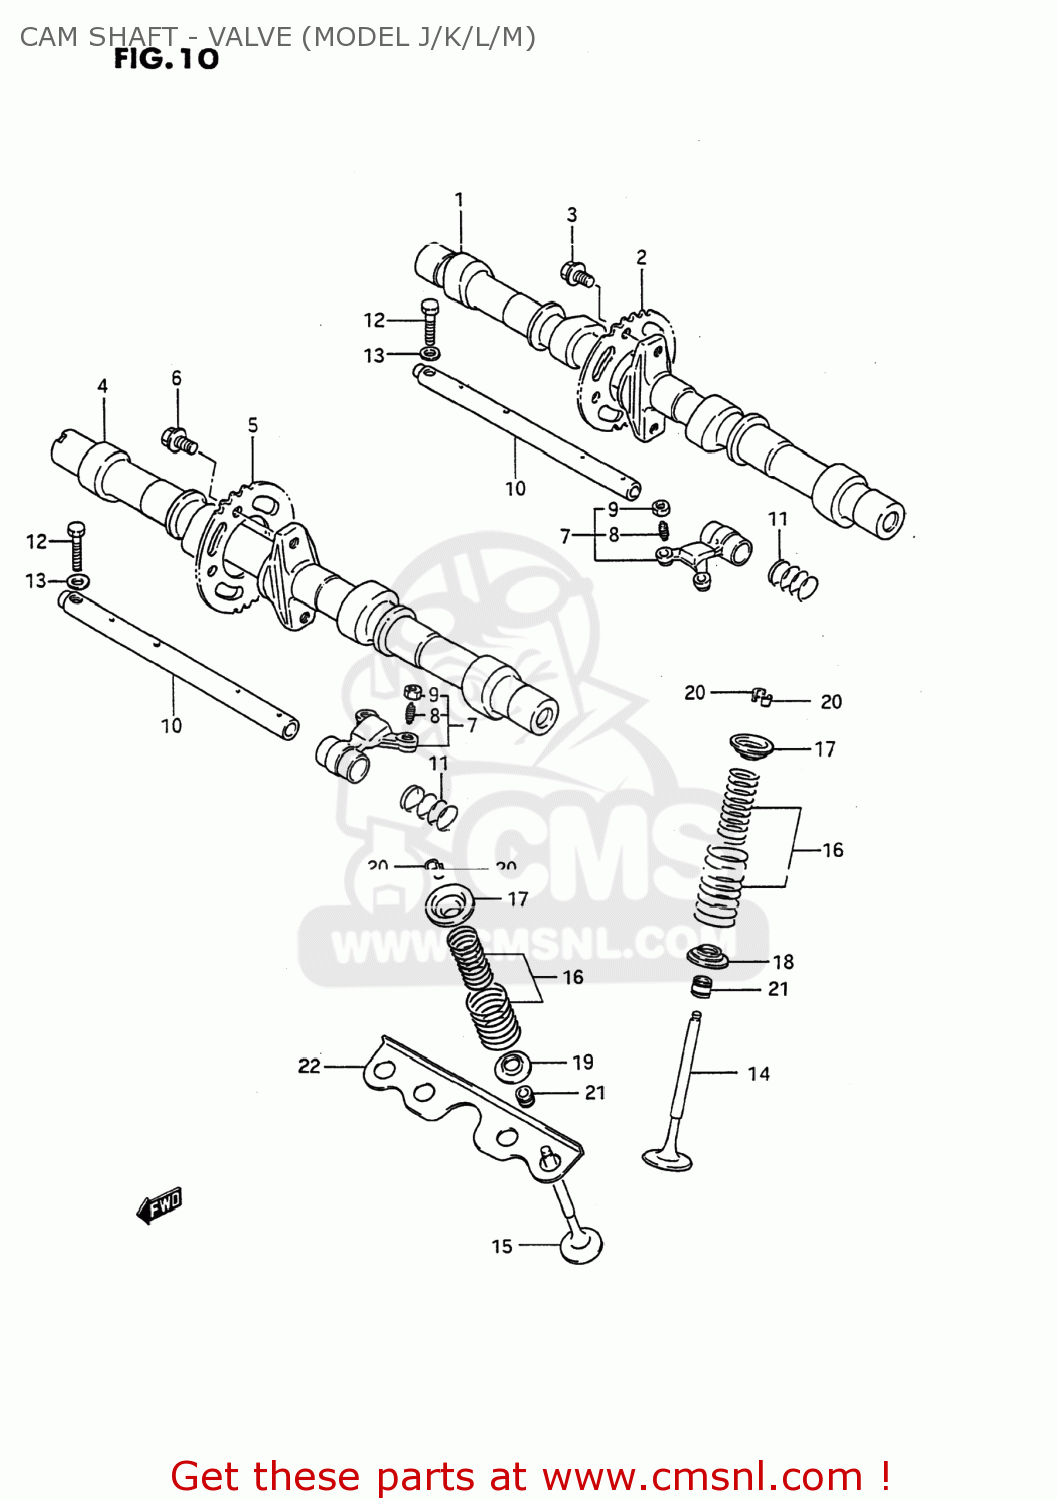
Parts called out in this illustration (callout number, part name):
1	CAMSHAFT,INTAKE
2	SPROCKET,CAMSHAFT
3	BOLT(7X11)
4	CAMSHAFT,EXHAUST
5	SPROCKET,CAMSHAFT
6	BOLT(7X11)
7	ARM,VALVE ROCKER
8	SCREW,TAPPET ADJUSTING
9	NUT,ADJUSTING
10	SHAFT,VALVE ROCKER ARM
11	SPRING
12	BOLT
13	WASHER, LOWER
14	VALVE,INTAKE
15	VALVE,EXHAUST
16	SPRING SET,VALVE
17	RETAINER,VALVE SPRING
18	SEAT,VALVE SPRING
19	SEAT,VALVE SPRING
20	COTTER VALVE
21	SEAL,OIL(5X10X9.7)
22	PLATE,VALVE SEAT
